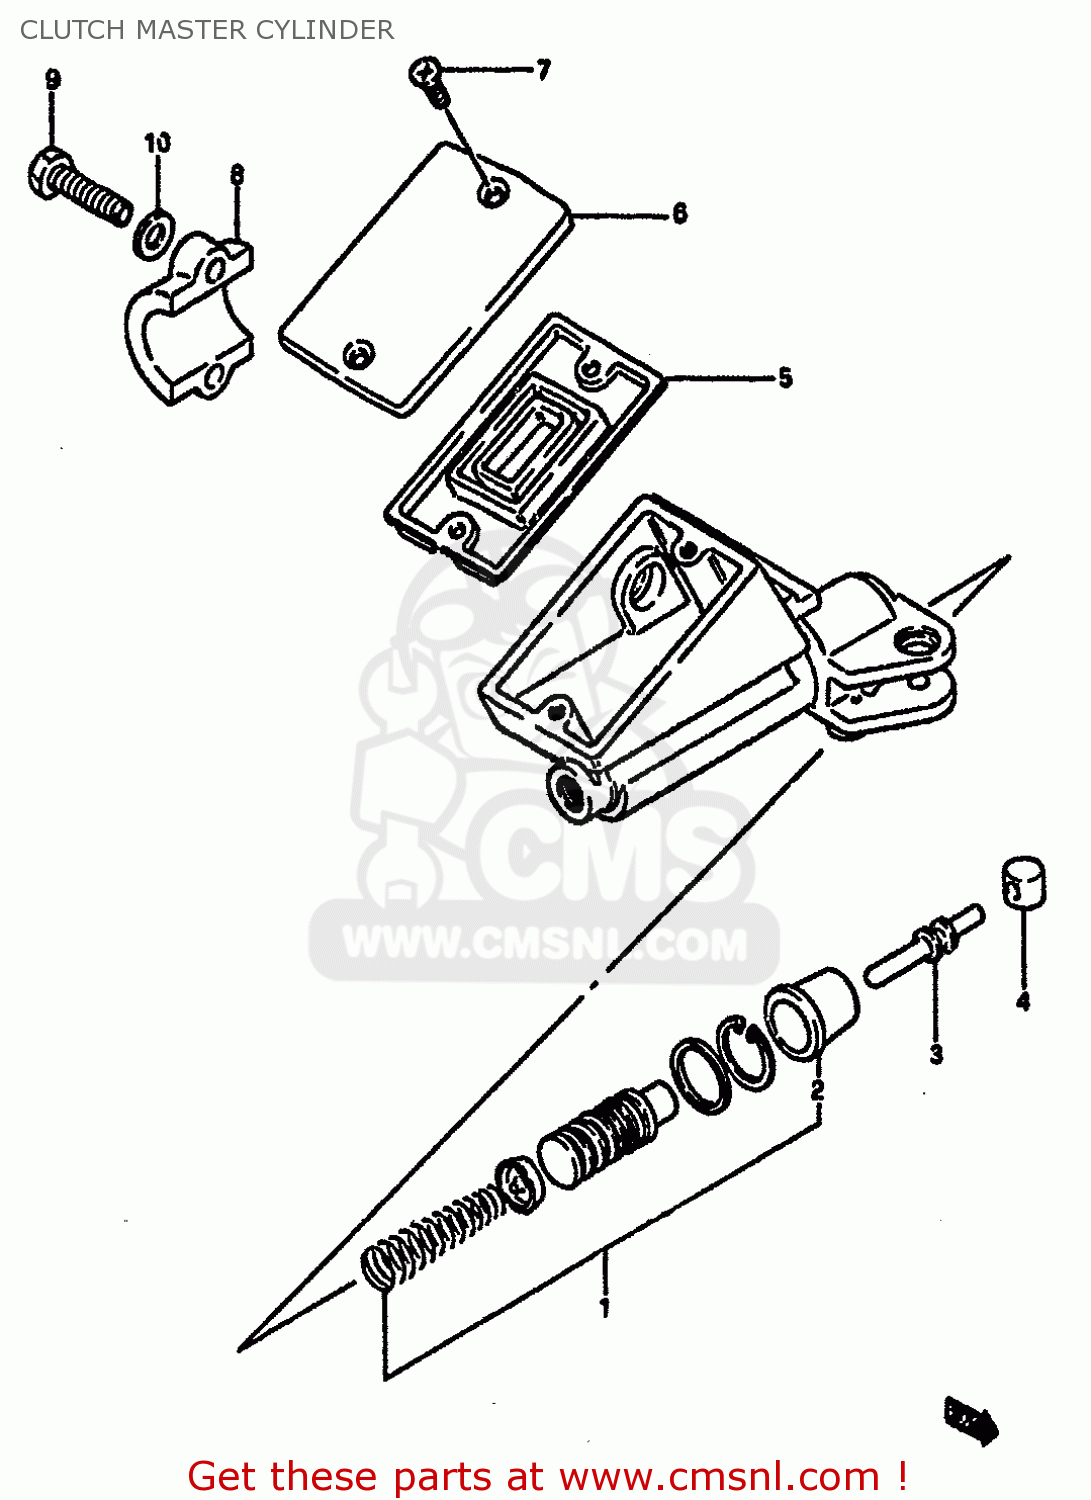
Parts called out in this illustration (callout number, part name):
1	PISTON & CUP SET
2	BOOT
3	ROD,PUSH
4	BUSH
5	6
6	CAP
7	SCREW
8	HOLDER,MASTER CYLINDER
9	BOLT
10	WASHER
